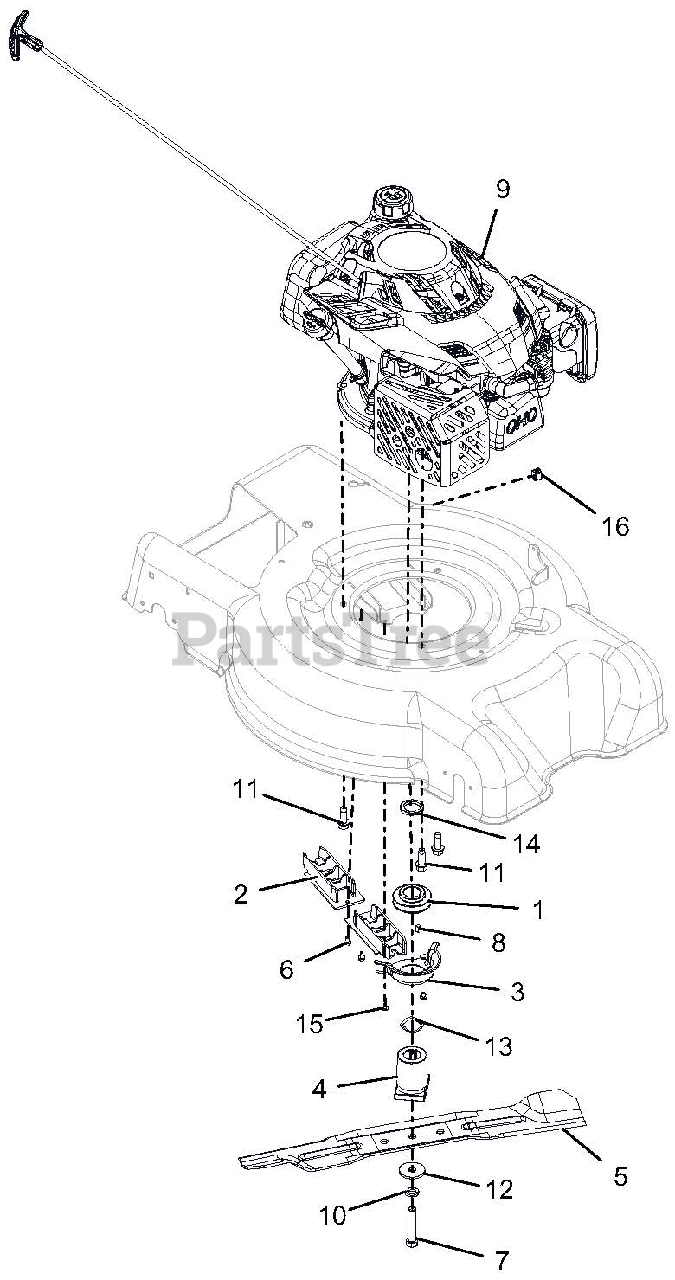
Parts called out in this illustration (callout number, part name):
1	PULLEY, GROUND DRIVE, LM
2	GUIDE, BELT INNER
3	GUIDE, BELT CRANK
4	ADAPTER, BLADE
5	BLADE, MOWER 21" HIGH LIFT
6	SCR-TAP 10-24X.375 PRE-COAT 80
7	@BLT-HEX .4375-20X2.25 GR8 YWZ
8	KEY-SQ .188X.188X.375
9	ENGINE, SUBARU 175CC VERT. ES
10	@WSHR-LK .44X.109 REG YWZC
11	@SCR-TAP .38-16X1.00 HWH TR YZ
12	WSHR-FL-STL .4375X1.50X.125 YZ
13	WASHER - WAVE 1.09X1.37X.016
14	SPCR, 1.00 X 1.375 X .179
15	SCR-TAP 10-24X.25 CRSLPH TR YZ
16	PLUG, DOME-BLACK, .625 DIA
